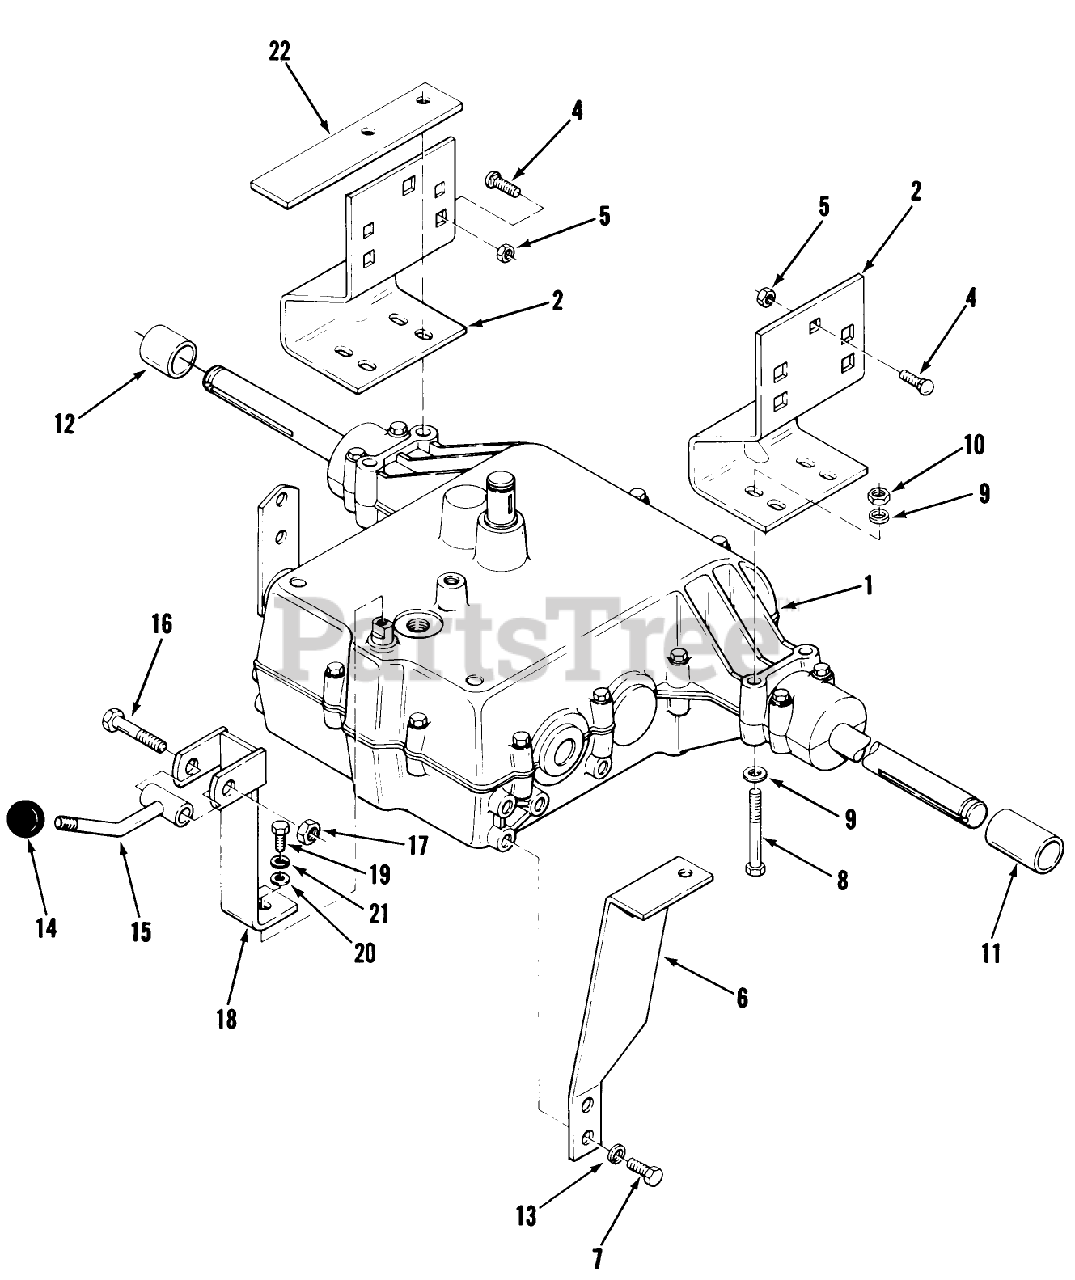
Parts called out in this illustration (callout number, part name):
1	ORDER FROM PEERLESS
4	CARRIAGE BOLT -4
6	TORQUE STRAP
7	Screw
9	WASHER 5/16 SAE
15	ASSY-UPPER SHIFT ROD
18	ASSY LEVER *R
20	WASHER
